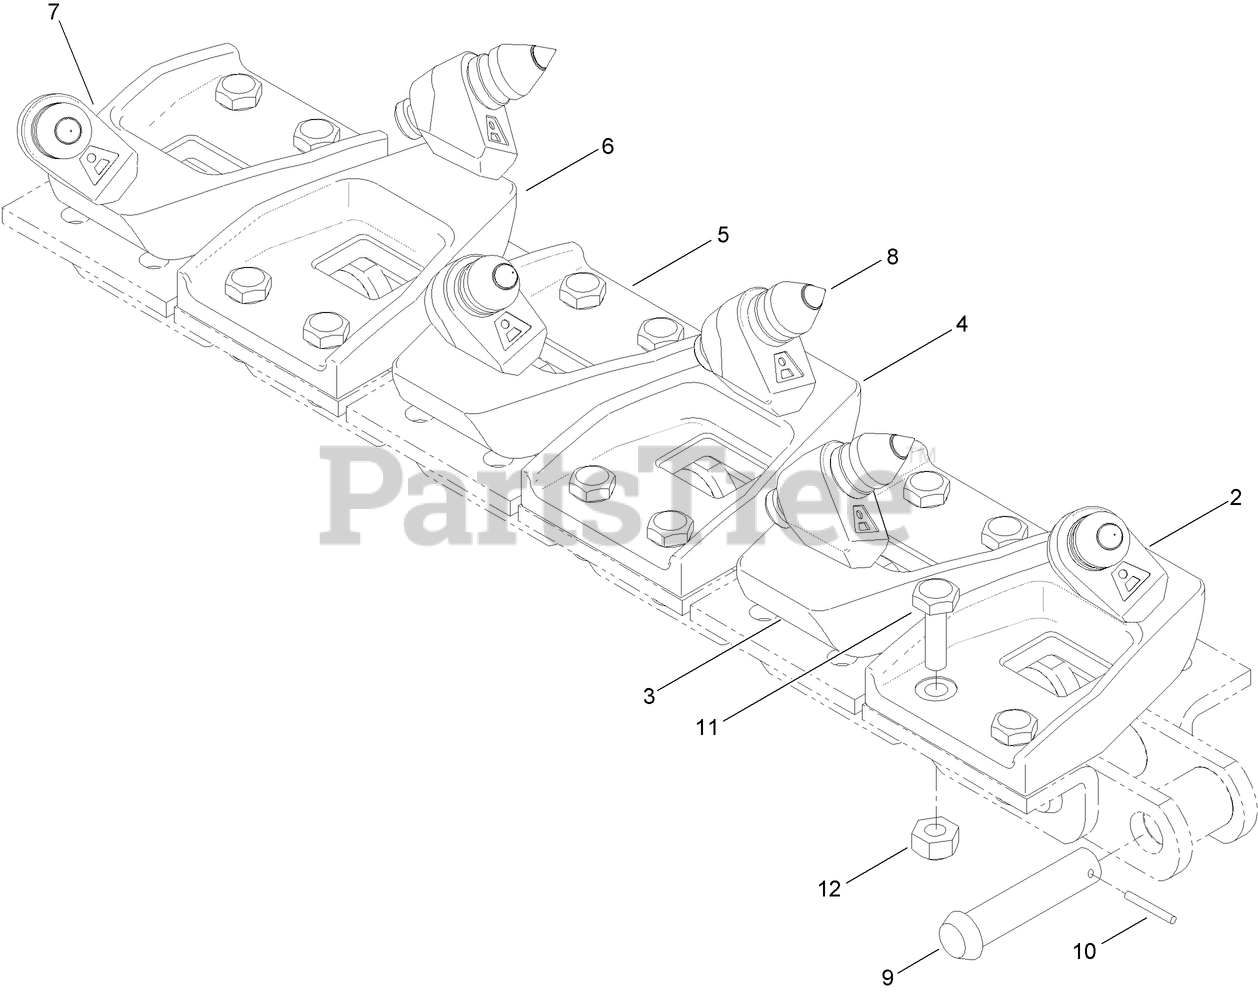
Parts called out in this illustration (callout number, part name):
2	TOOTH-ROCK (1" L)
3	TOOTH-ROCK (1" R)
4	TOOTH-ROCK (3" L)
5	TOOTH-ROCK (3" R)
6	TOOTH-ROCK (6" L)
7	TOOTH-ROCK (6" R)
8	BIT-CONICAL
9	PIN-MASTER
10	PIN-KEEPER, MASTER
12	NUT-LOCK
